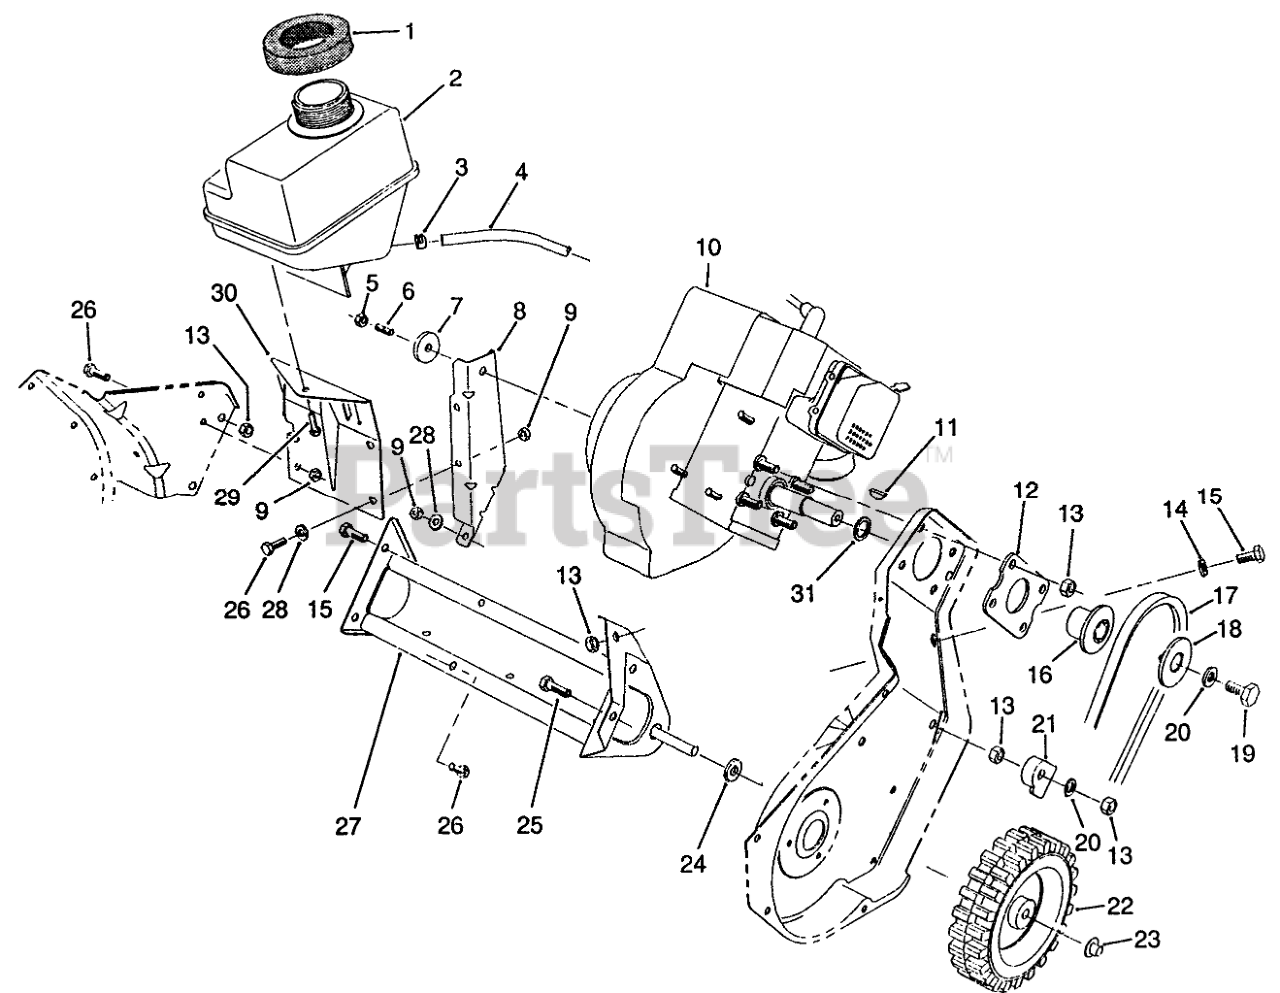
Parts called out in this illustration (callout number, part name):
1	SEAL-FOAM
2	Tank-Gas
3	Clamp
4	LINE-FUEL
5	NUT-LOCK, CONE
7	WASHER-SUPPORT, ENGINE
8	Support-Engine
9	NUT-LOCK, NI
11	KEY-WOODRUFF
12	Plate Engine
13	NUT-LOCK, NI
14	WASHER-PLAIN
15	SCREW-HH
16	Hub-HALF SHEAVE
17	Belt-Drive
18	CAP-HALF SHEAVE
19	SCREW-HH
20	WASHER-FLAT
21	Guide-Cable
22	WHEEL
23	RETAINER-PUSH ON
24	SPACER-PLASTIC
25	SCREW-HH
26	SCREW-HH
27	Frame Assembly
28	WASHER-FLAT
29	SCREW-SHWH, THREAD FORMING
30	Bracket-Fuel Tank
31	WASHER
